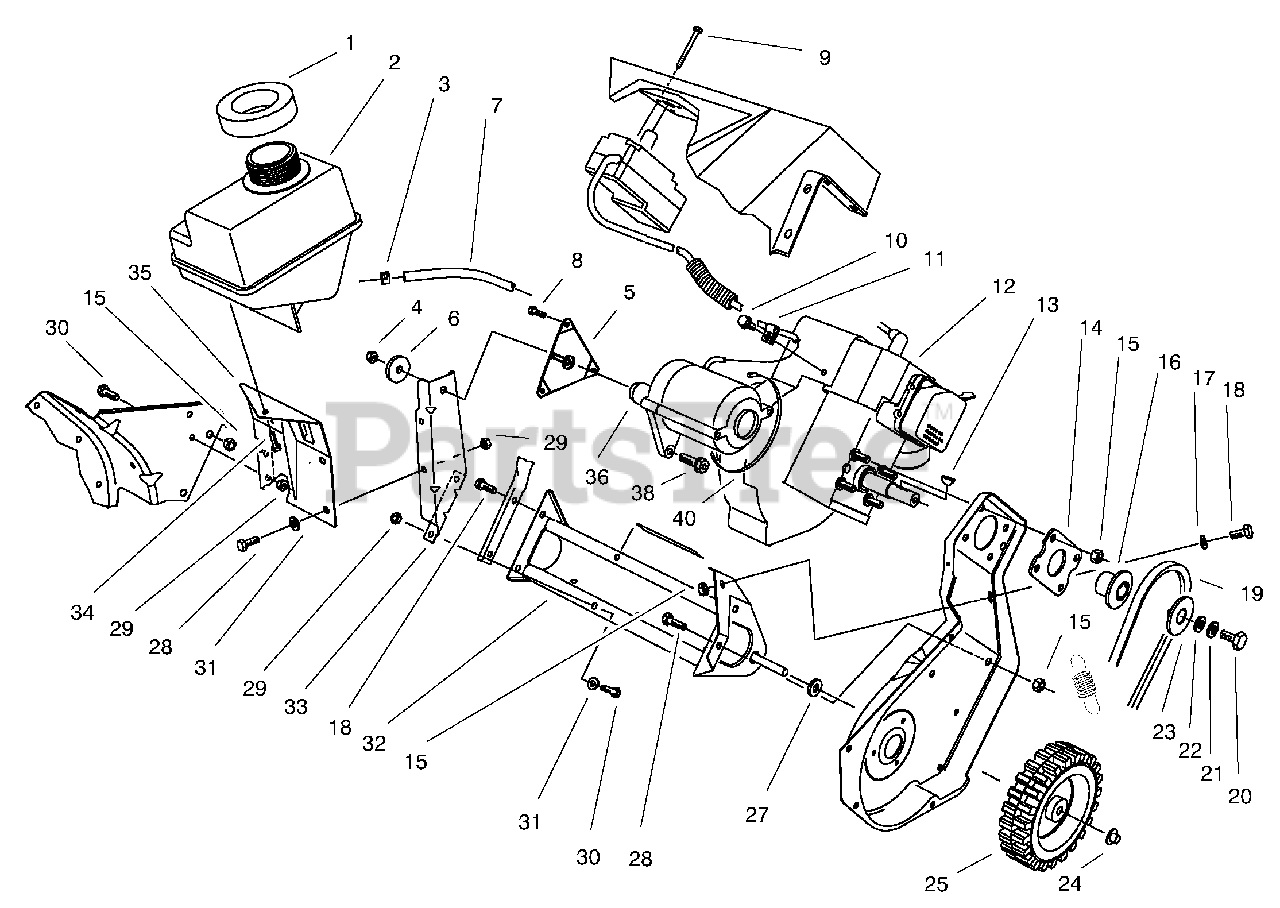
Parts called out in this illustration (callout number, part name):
1	Seal-Fuel Tank
2	Tank-Fuel
3	Clamp-Hose
4	Nut-Lock
5	Bracket & Stud Assembly
6	Washer-Engine Support
7	Hose-Fuel
8	Screw-Thread Forming
9	Screw-Thread Forming
10	Screw-Thread Forming
11	Clamp-Cable
13	Key-Woodruff
14	Plate-Engine
15	Nut-Lock
16	Hub-Sheave
17	Washer-Flat
18	Screw-Hex. Hd.
19	Belt-Drive
20	Screw-Locking Hex. Hd.
21	Washer-Belleville
22	Washer-Flat
23	Cap-Sheave
27	Spacer-Wheel
28	Screw-Hex. Hd.
29	Nut-Lock
30	Screw-Hex. Hd.
31	Washer-Flat
32	Frame Assembly
33	Support-Engine
34	Screw-Thread Forming
35	Bracket-Fuel Tank
36	Starter Motor Assembly
38	Screw-Hex. Torx
40	Strap-Starter Tie Down
